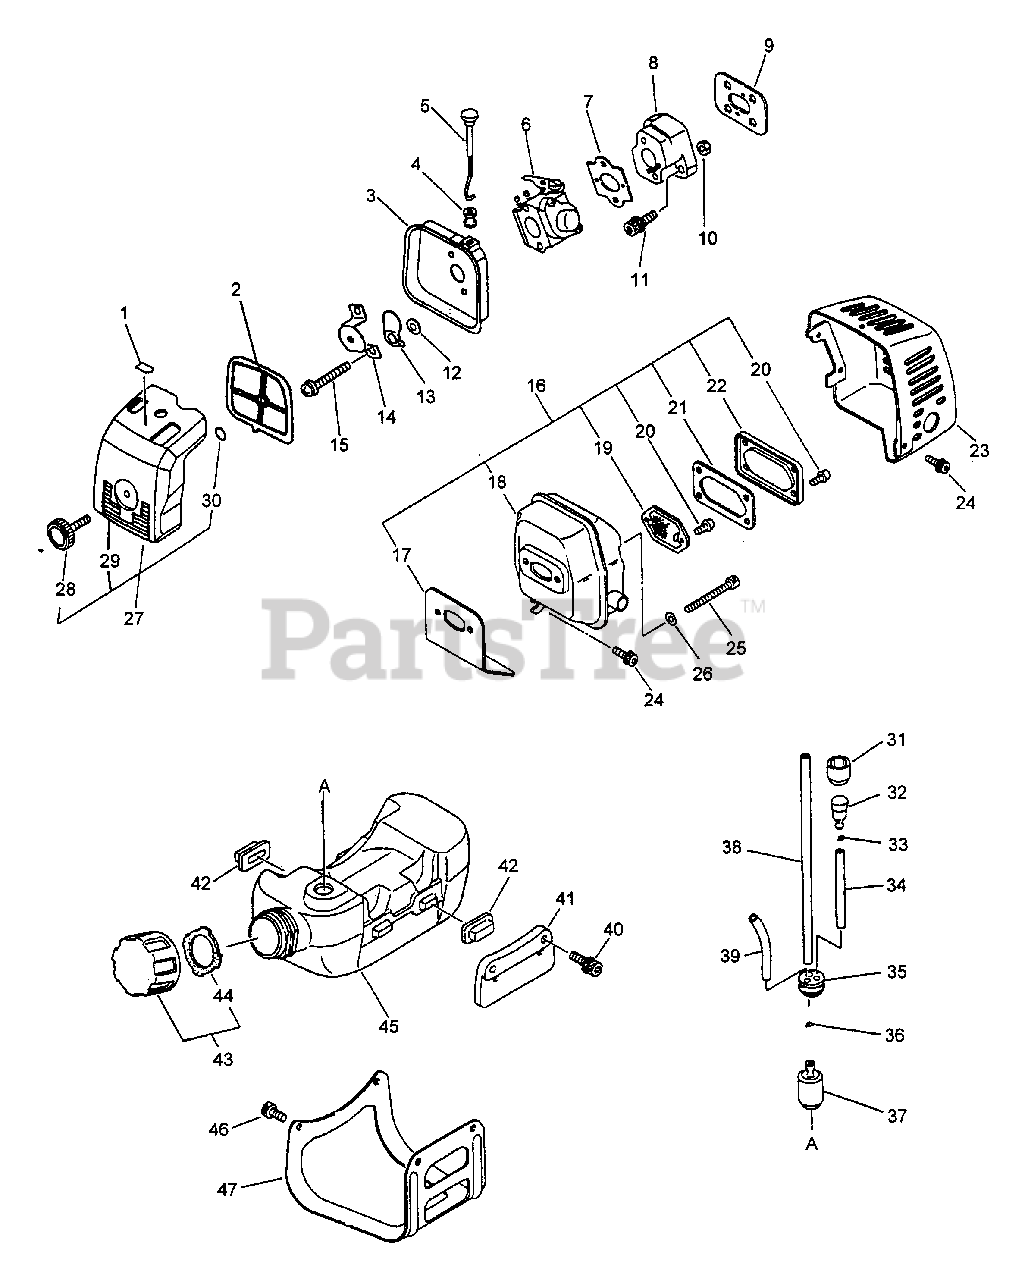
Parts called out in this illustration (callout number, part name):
1	LABEL - CHOKE
2	FILTER, AIR - HEAVY DUTY
3	CASE, AIR FILTER
5	ROD, CHOKE
6	CARBURETOR WT-333
6	CARBURETOR WT-344
7	GASKET, INTAKE
8	INSULATOR, INTAKE
9	GASKET, INTAKE
11	SCREW - 5X25
12	WASHER - 5
13	SHUTTER, CHOKE
14	PLATE, PREVENT
15	SCREW - 5X57
16	MUFFLER ASSY
17	GASKET, EXHAUST
18	MUFFLER
19	SCREEN, SPARK ARRESTOR
20	SCREW - 4X10
21	GASKET, EXHAUST
22	GUIDE, EXHAUST
23	COVER, MUFFLER
24	SCREW - 5X12
25	SCREW - 5X60
26	WASHER - 5
27	AIR FILTER COVER ASSY
28	THUMBSCREW
29	COVER, AIR FILTER
30	O-RING - 3
31	COVER, VENT
32	VENT, FUEL TANK
33	CLIP - 5.5
34	PIPE - 3X5X50
35	GROMMET
36	CLIP - 6
37	FILTER, FUEL
38	PIPE - 3X5X180 -- BLACK
39	PIPE - 3X6X90 -- CLEAR
40	SCREW - 5X20
41	BRACKET, FUEL TANK
42	CUSHION, FUEL TANK
43	CAP ASSY
44	GASKET, CAP
45	TANK, FUEL
46	SCREW - 5X12
47	GUARD, FUEL TANK
